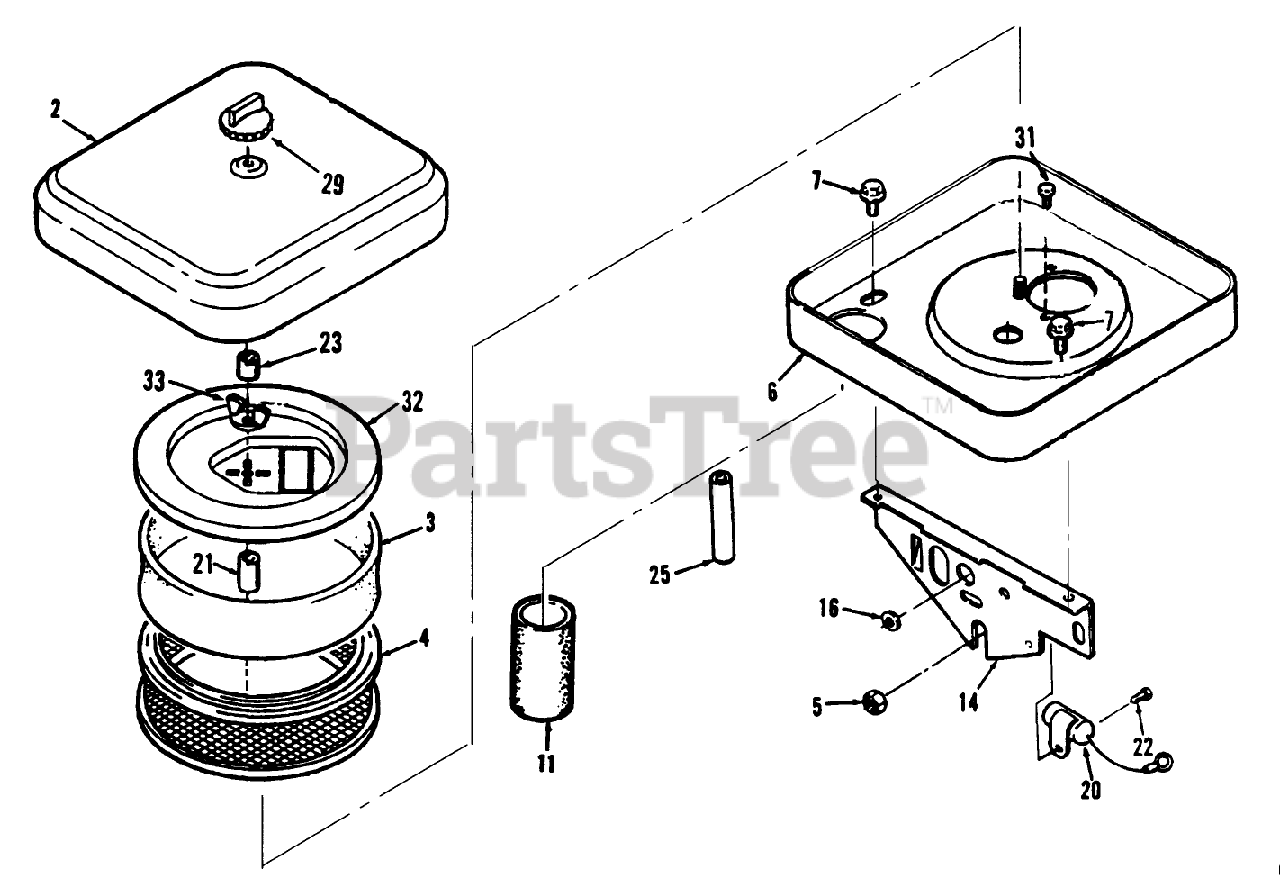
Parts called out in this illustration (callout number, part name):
3	AIR CLEANER ELEMENT
7	SCREW-TAPPING
14	SUPPORT-AIR CLEANER
20	Capacitor (300 VD)
